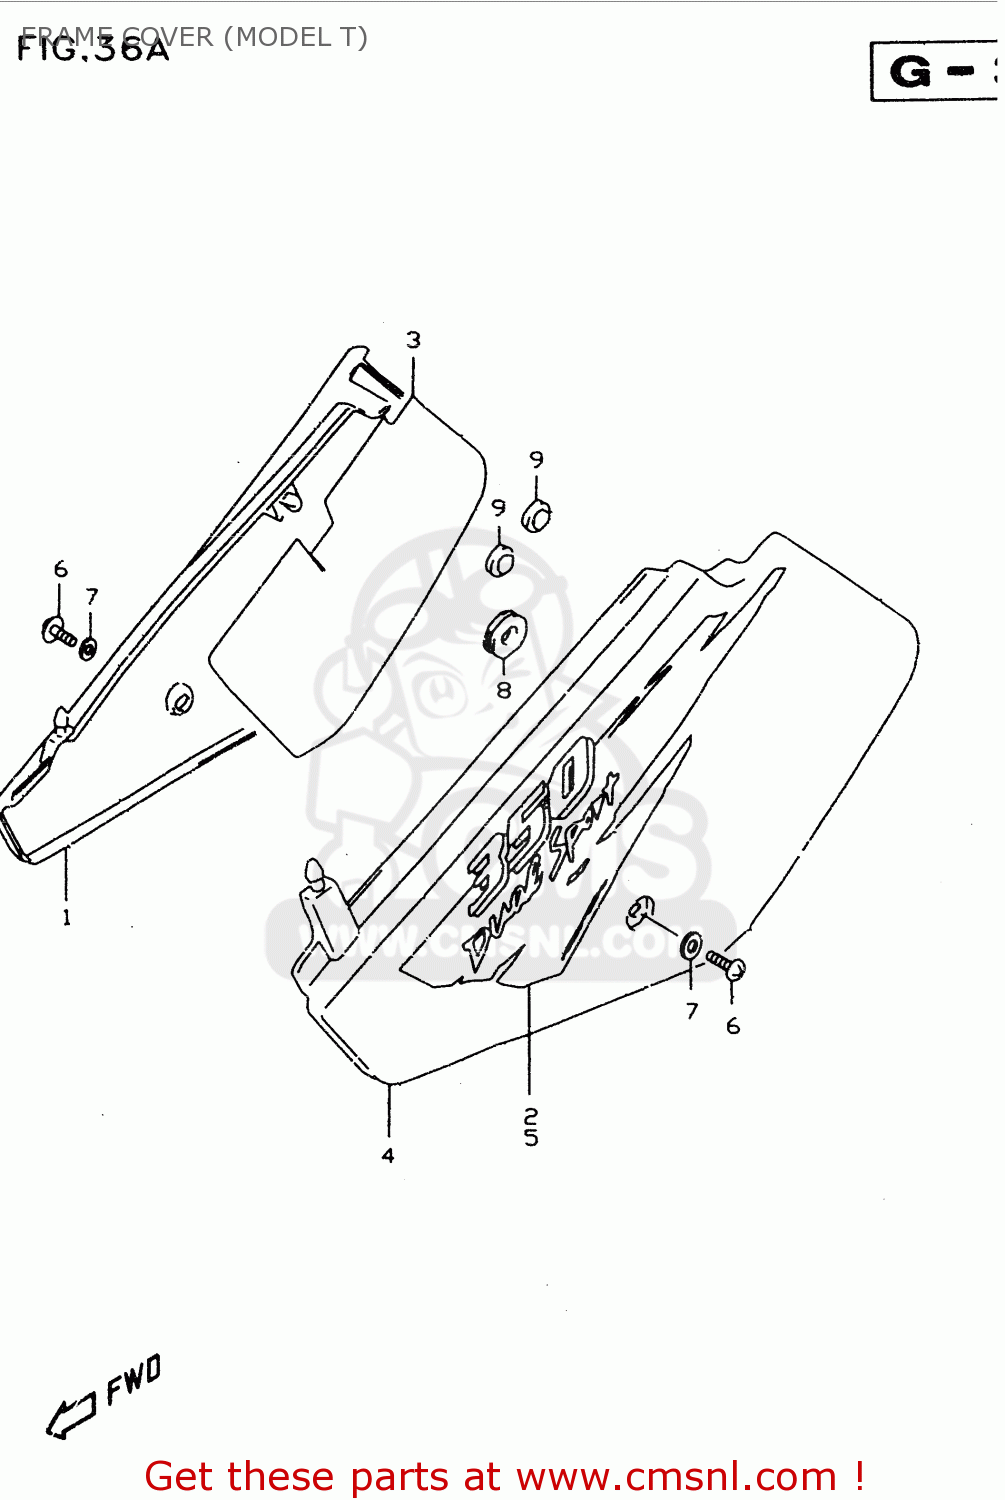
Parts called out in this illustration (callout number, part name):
1	COVER,FRAME,R(WHITE)
2	EMBLEM, RH
3	SHIELD,FRAME COVER,R
4	COVER,FRAME,L(WHITE)
5	TAPE,FRAME COVER,LEFT
6	SCREW
7	WASHER
8	CUSHION
9	CUSHION
